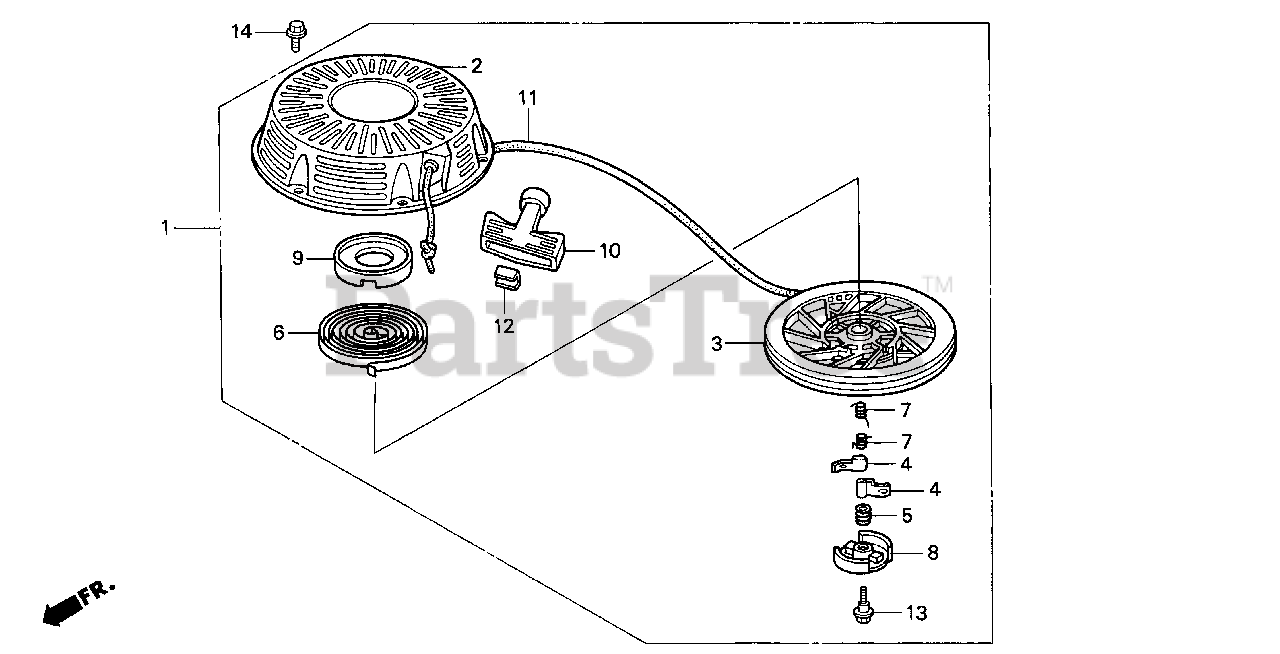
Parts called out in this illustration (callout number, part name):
1	STARTER ASSY., RECOIL *R8* (BRIGHT RED)
1	STARTER ASSY., RECOIL *NH1* (BLACK)
2	CASE, RECOIL STARTER *R8* (BRIGHT RED)
2	CASE, RECOIL STARTER *NH1* (BLACK)
3	PULLEY, RECOIL STARTER
4	RATCHET, STARTER
5	SPRING, FRICTION
6	SPRING, STARTER RETURN
7	SPRING, RATCHET
8	RETAINER, SPRING
9	HOLDER, SPRING
10	GRIP, STARTER
11	ROPE, RECOIL STARTER (N/A: USE P/N 08560-ZG921-11)
12	GRIP, REINFORCEMENT
13	SCREW, CENTER
14	BOLT, FLANGE (6X8)
